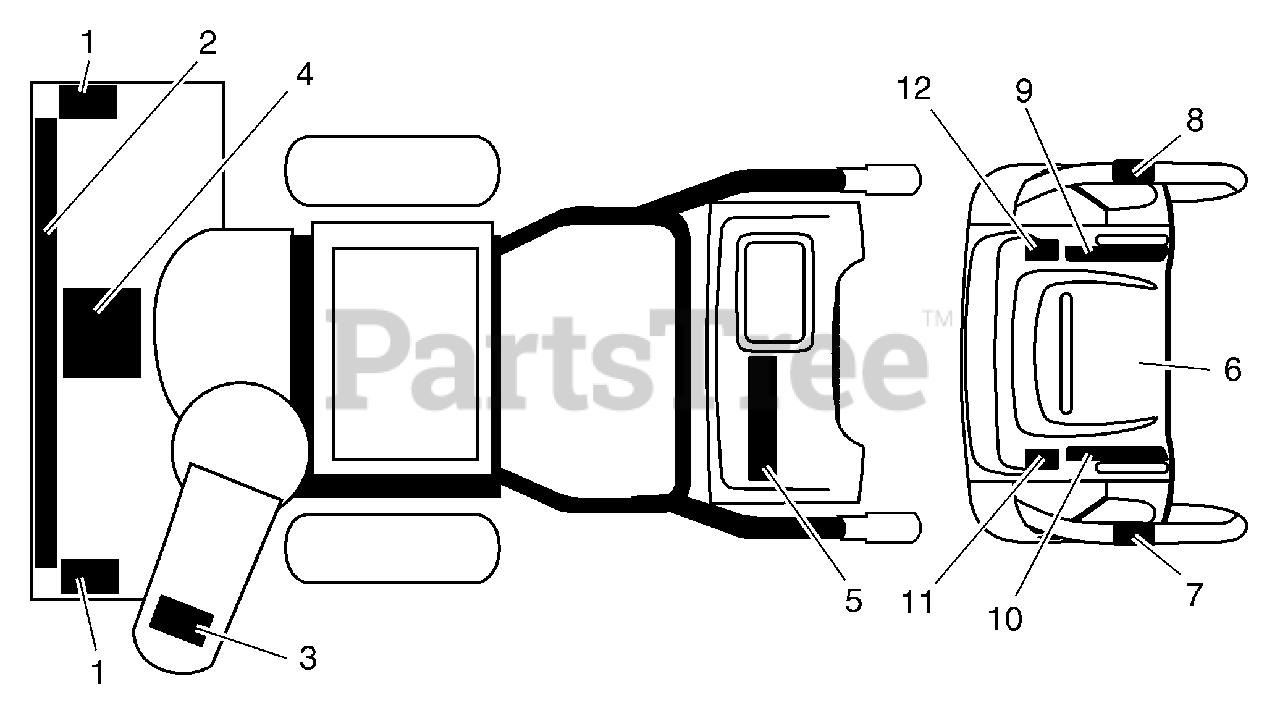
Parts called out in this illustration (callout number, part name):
1	Decal, Danger
2	Decal, Poulan Pro, 11HP/30" (large)
3	Decal, Danger, Deflector
4	Decal, Danger
5	Decal, Poulan Pro, 11HP/30" (small)
6	Decal, Instruction
7	Decal, Traction Lever
8	Decal, Auger Lever
9	Decal, Speed Control
10	Decal, Remote Deflector
11	Decal, LH Trigger
12	Decal, RH Trigger
